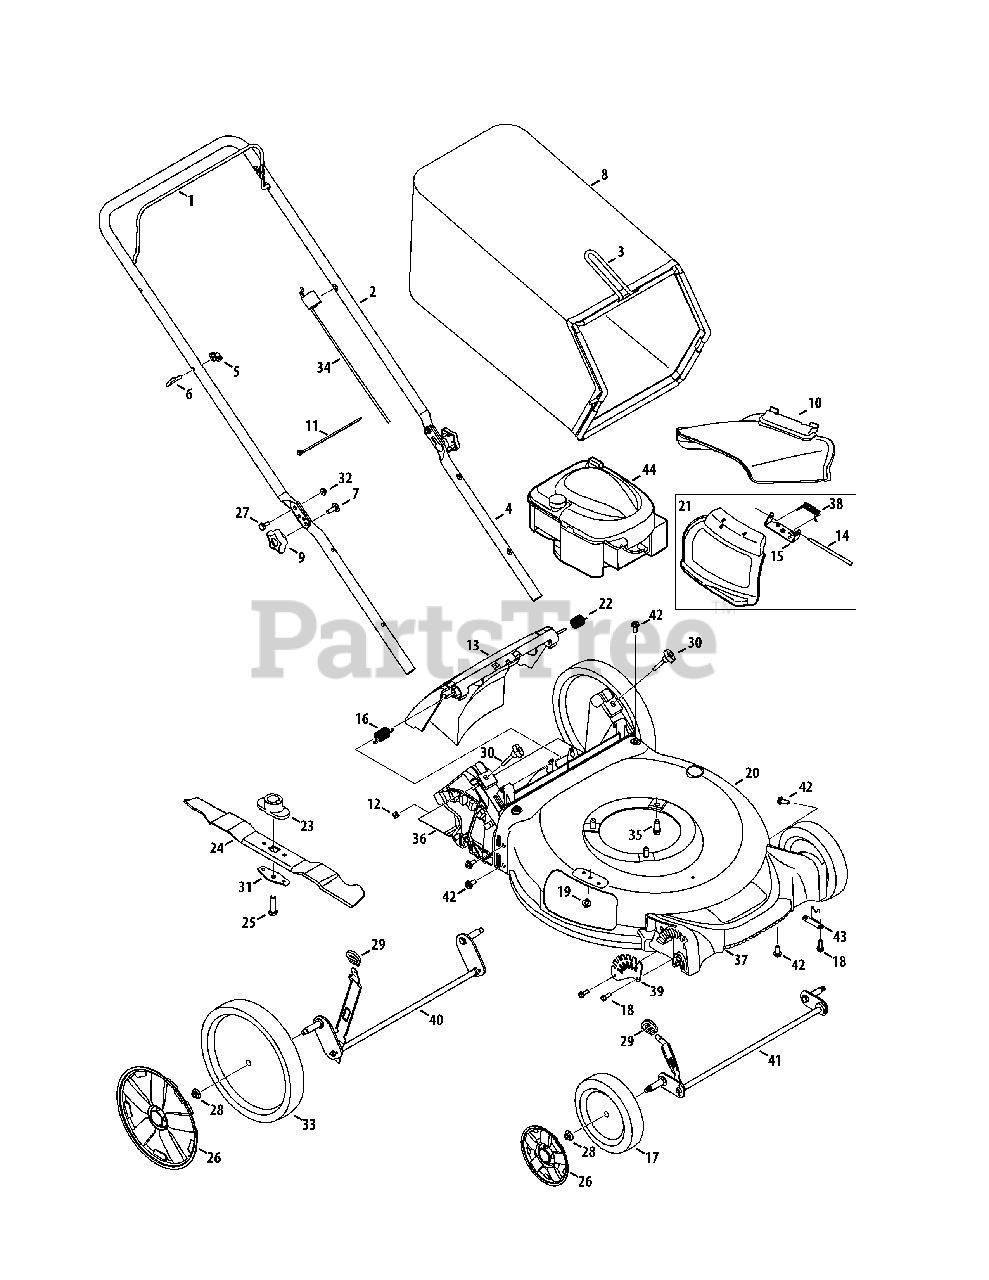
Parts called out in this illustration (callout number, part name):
1	Blade Control
2	Upper Handle
4	Lower Handle
5	Wing Nut
6	Rope Guide
7	Carriage Screw ,5/16-18
8	Grass Bag
9	Hand Knob
10	Side Chute
11	Cable Tie
12	Nut, Sq., 1/4-20
13	Rear Discharge Door Assembly
14	Hinge Pin
15	Chute Deflector Bracket
16	Torsion Spring - RH
17	Wheel, 7 x 2
18	Screw, 1/4-15 x .750
19	Screw, 1/4-20 x .500
20	Deck - 21"
21	Hinged Mulch Plug Assembly
22	Torsion Spring - LH
23	Blade Adapter
24	Mulching Blade
25	Screw , 3/8-24 x 1.50
26	Hub Cap - Front
26	Hub Cap - Rear
27	Sldr. Screw, .375 x .126 x 1/4-20
28	Flange Lock Nut, 3/8-16
29	Adjustment Lever Knob
30	Wing Nut
31	Blade Bell Support
32	Nut, Flange Lock, 1/4-20
33	Wheel, 11 x 2
34	Control Cable
35	TT Sems Screw, 3/8-16 x 1.0
36	Trail shield
37	Front Cover
38	Torsion Spring
39	Front Height Adjuster Plate
40	Rear Axle Assembly
41	Front Axle Assembly
42	Screw, 5/16-14 x .750
43	Axle Retainer Bracket
44	Engine - 126L02-0864-F1
